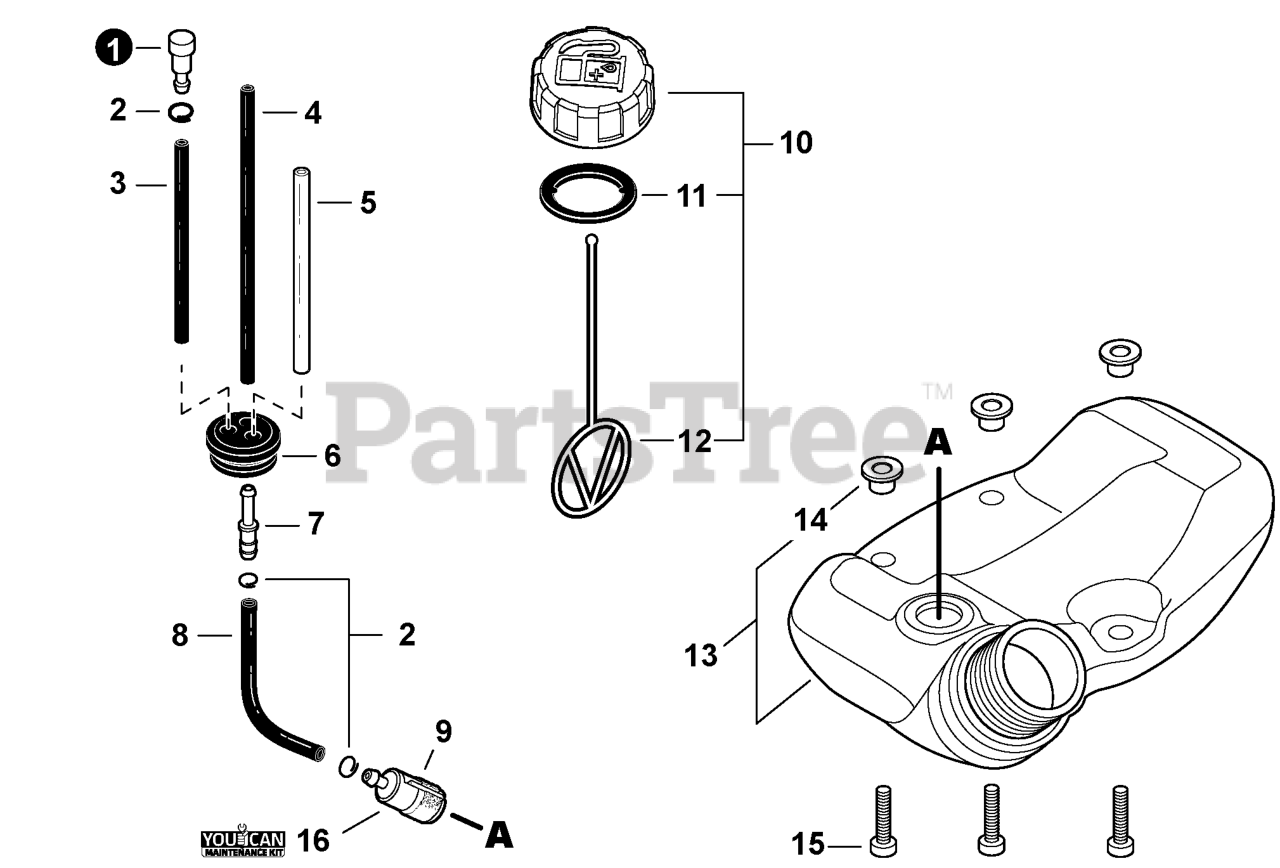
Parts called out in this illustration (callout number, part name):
1	VENT ASSY
3	PIPE, FUEL 3x6x80 YELLOW
4	PIPE, FUEL 3x5x90 BLACK
5	PIPE, FUEL 3x5x74 BLACK
6	GROMMET, FUEL 5
7	CONNECTOR, PIPE 5x3.5
8	PIPE, FUEL 3x5x110 BLACK
9	FILTER, FUEL
10	CAP ASSY, FUEL
11	GASKET, FUEL CAP
12	CONNECTOR, CAP L= 123
13	TANK ASSY, FUEL
14	COLLAR 5
15	BOLT, TORX 5x20
16	TUNE-UP KIT - YOUCANT
